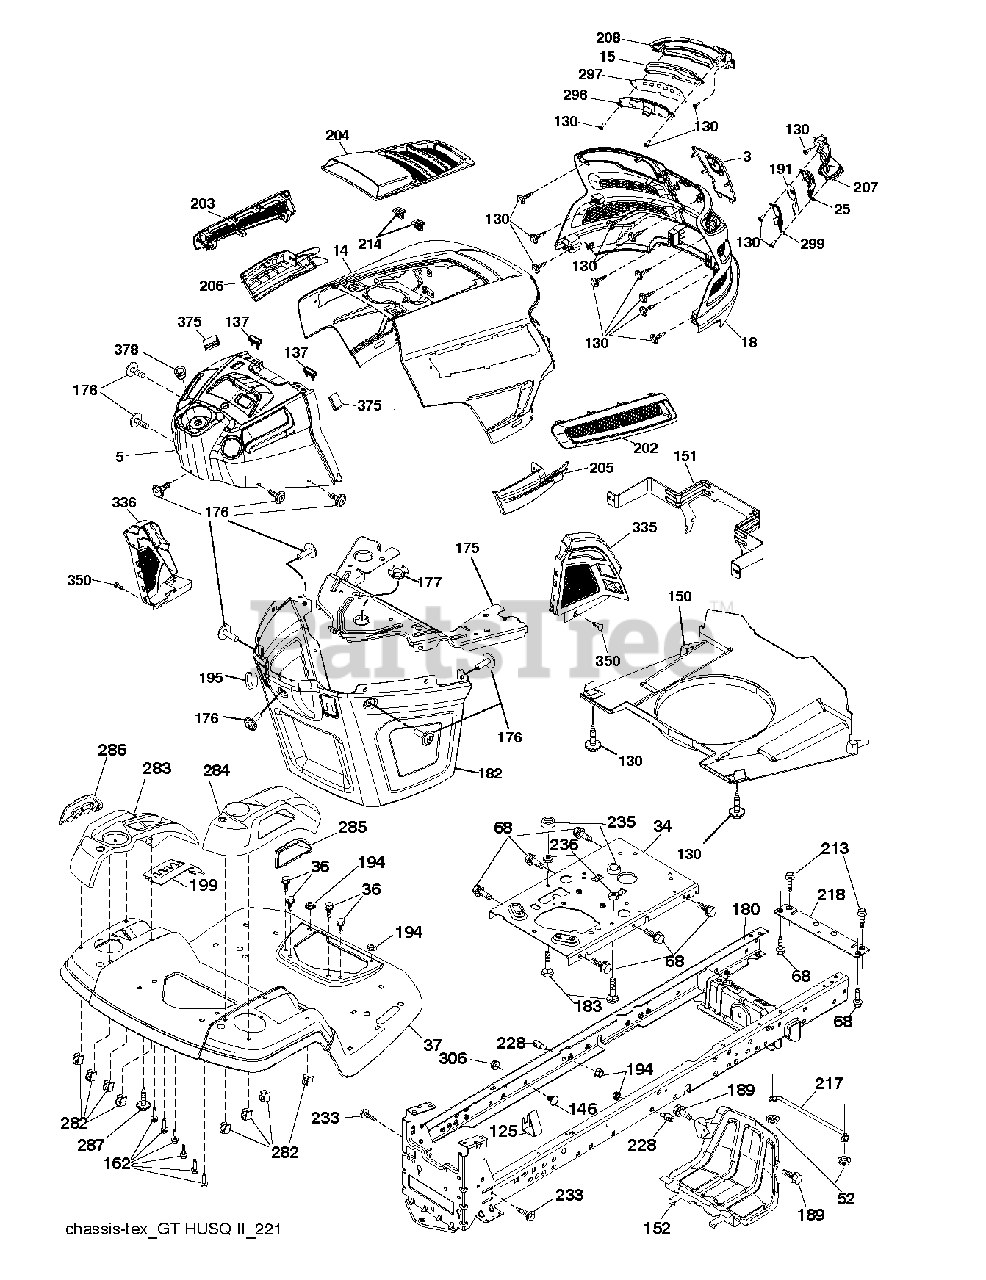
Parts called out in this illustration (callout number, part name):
3	APPLIQUE.SUBASM.GT.HUSQ.II
5	DASHBOARD.TEX.GT2.UPPER.S.PTO
14	HOOD.ASM.HUSQVARNA.GT.TEX.ORAN
15	LED LIGHT.LH
18	GRILLE SUBASM.GT.II.LOW.HDLGHT
25	LENS.RH
34	PLATE.ENGINE.WELDED.CHASSIS
36	SCREW 5/16"
37	FENDER.TLT.FS.W/CUPHLD.ORANGE
52	LOCKNUT
68	SCR 5/16-18 X 1/2 SELFTAP ZN
125	CLIP.FUEL.LINE
130	SCREW.#10 X 0.750.BOS
137	BUMPER DASH
146	BOLT.RDHD.SHT.SQNK.3/8-16X5/8
150	AIR.DUCT.GTV.BLACK
151	BRACKET.PIVOT.HOOD.GT.HUSQ.II
152	SHIELD.BROWNING.PNT.GT.V2
162	SCREW.HI-LO.CONSOLE
175	Crossmember Plate
176	SCREW.#10-24X5/8.RN.QU
177	BUSHING STEERING
180	CHASSIS
182	DASH.LOWER.COMMON.12V.ADAPTOR
183	BOLT.5/16-18X1-1/4 FULL THD
189	SCREW
191	INSERT INFLECT.RH
194	NUT LOCK HEX FLANGE 5/16-18
195	PLUG.HOLE.DASH.LOWER.12V.BLK
199	PLATE.DECK.LIFT.HUSQ.LT
202	VENT.SIDE.RH.GT.HUSQ.II.
203	VENT.SIDE.LH.GT.HUSQ.II.498
204	VENT.TOP.HUSQ.GT2
205	SIDE.TRIM.RH.GT.HUSQ.II
206	SIDE.TRIM.LH.GT.HUSQ.II.GRAY
207	BEZEL GT2 LED RH W/ LOWER.ATT
208	BEZEL GT2 LED LH W/ LOWER ATT
213	BOLT
214	CLIP.RETAINER.TINNER.
217	ROD.PIVOT.HOOD
218	X-PIECE.HOOD.STOP.NON/
228	STUD.FASTNER.W/ANTI-ROTATE
233	BOLT.SHOULDER
235	SPACER FENDER
236	NUT.CENTERLOCK.5/16-
282	CLIP.RETAINER.CONSOLE.LT.HUSQ
283	CONCOLE.CNTRL.PDL.HUSQ.LT.498
284	CONSOLE.ASM.LFT.RSF.HUSQ.LT
285	CONSOLE INSERT RH
286	CONSOLE.INSRT.LH.HUSQ.LT.BLACK
287	SCREW 1/4X20
296	LED LIGHT.LH
297	INSERT REFECT LH
299	LED LIGHT.RH
306	NUT LOCK FLG 3/8-16 UNC
335	COVER.LOWER.DASH.RH.BLACK
336	COVER-LH.LOWER.DASH.GT2.BLACK
350	CLIP.X-MAS.TREE
375	BUMPER CLIP-ON. DASH 1"
378	BUSHING FLANGE; PLASTIC
